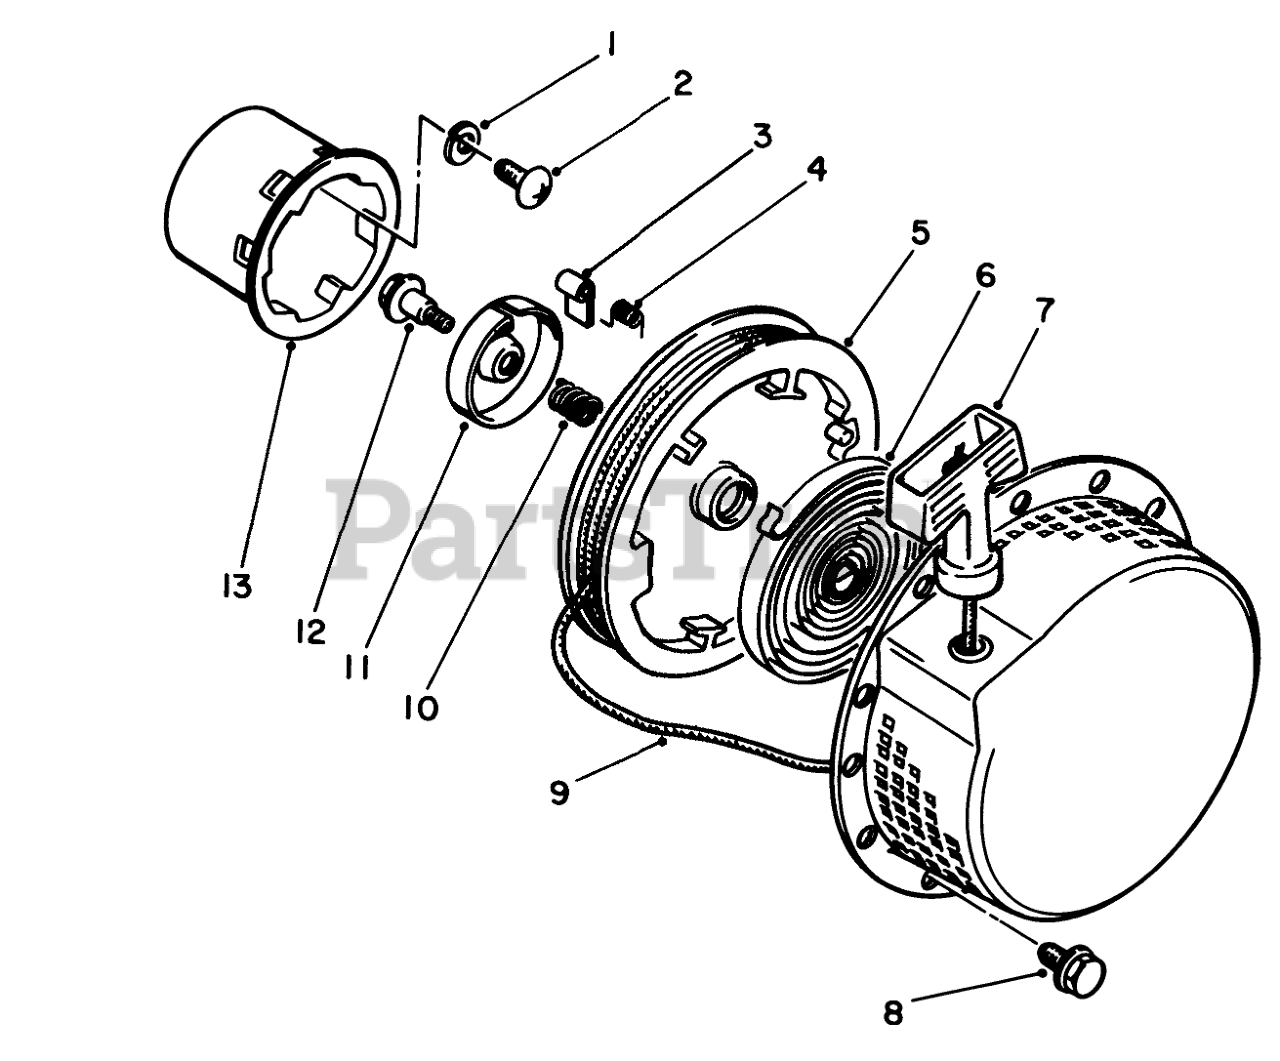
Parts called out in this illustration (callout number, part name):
1	Washer-Lock
2	Screw
4	SPRING
6	SPRING
7	Grip-Hand
9	Starter Rope Assembly (Incl. Ref. #7)
10	SPRING
11	RETAINER
13	Pulley
